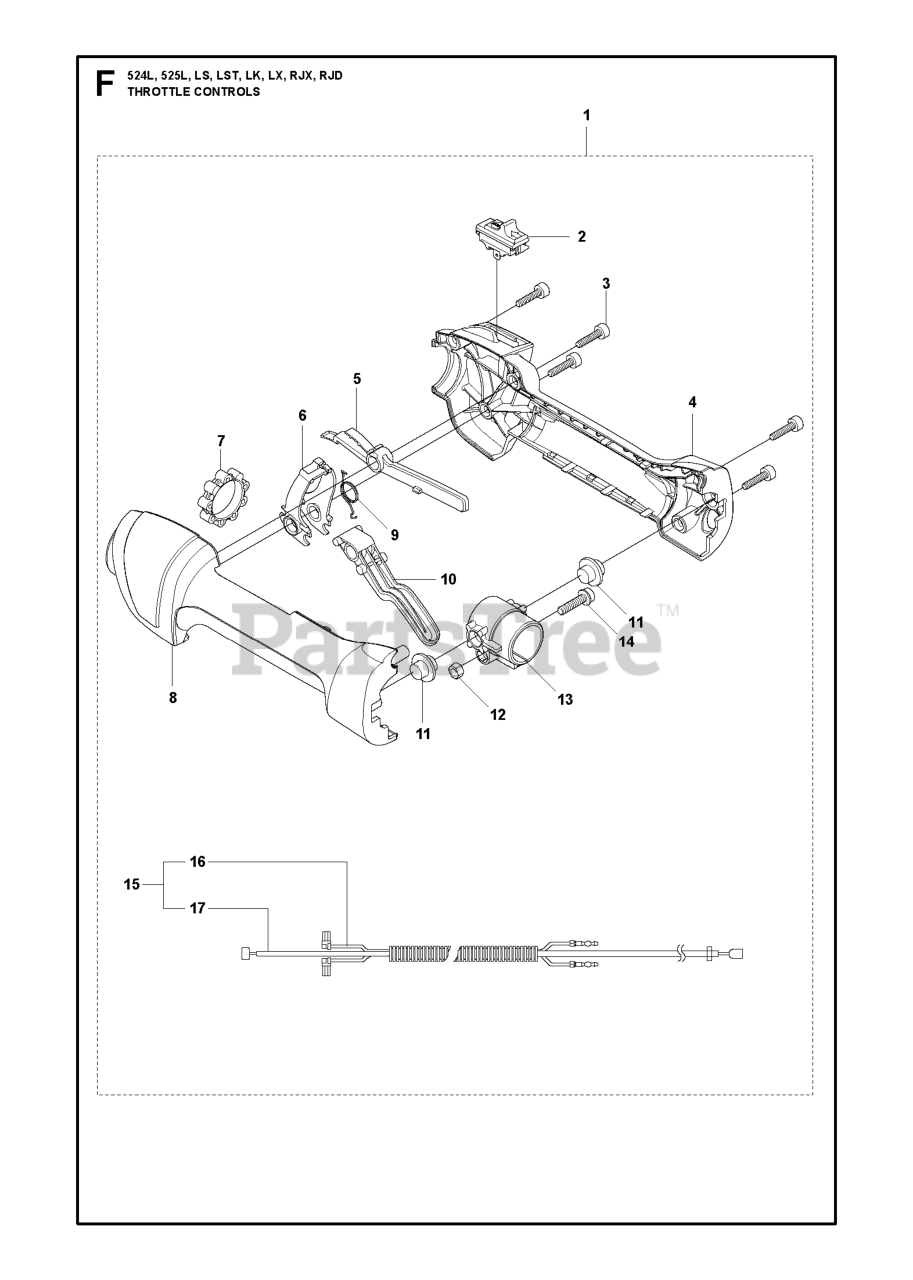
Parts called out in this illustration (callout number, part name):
1	ASSY THROTTLE CONTROL
2	STOP BUTTON
4	HANDLE
5	THROTTLE LOCK
7	VIBRATION DAMPER
8	HANDLE
9	RETURN SPRING
10	THROTTLE TRIGGER
11	DAMPER
13	RETAINER
15	WIRING ASSY
16	SHORT CIRCUIT CABLE
17	THROTTLE CABLE
